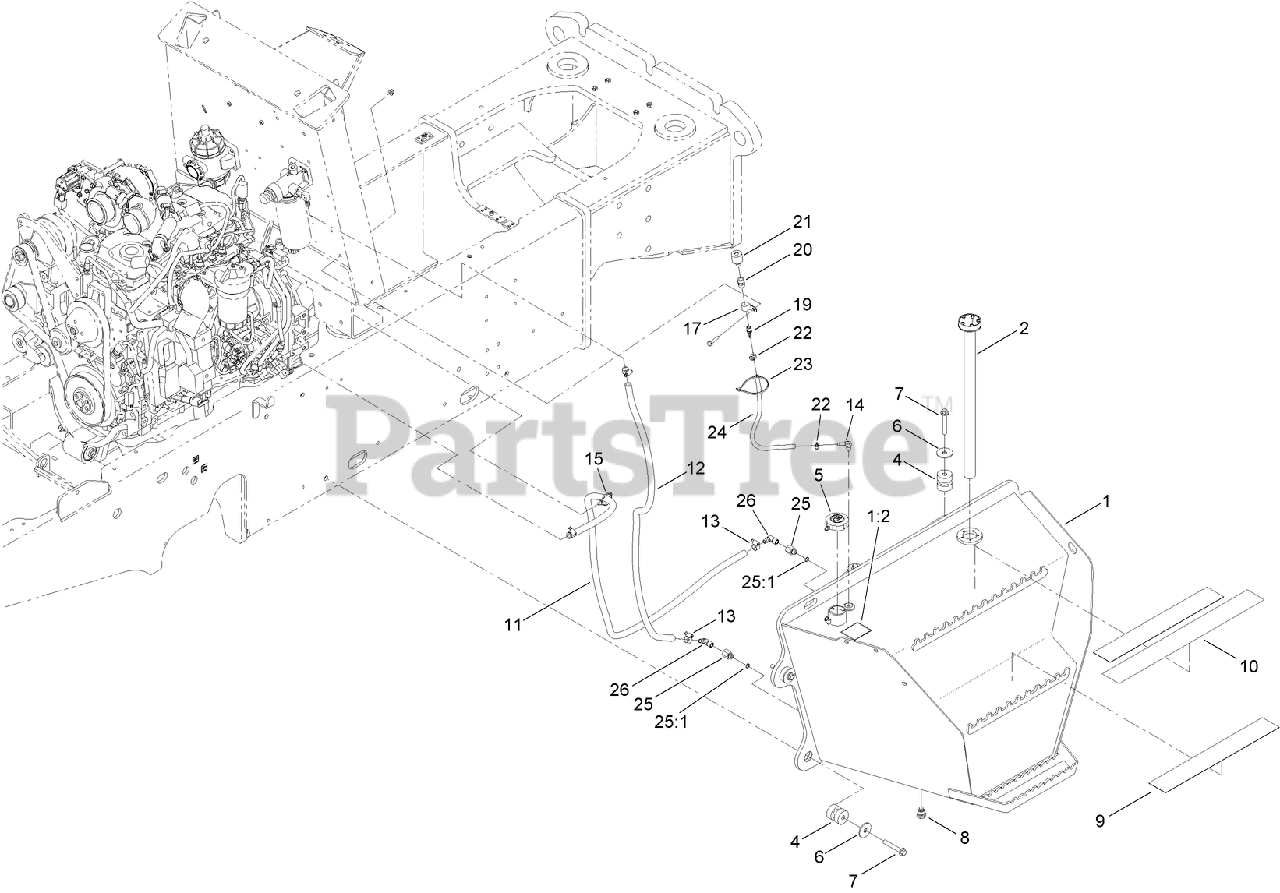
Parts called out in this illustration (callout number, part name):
1	FUEL TANK ASM
1:2	DECAL-DIESEL, ULTRA-LOW
2	SENDER-FUEL
4	ISOLATOR-MOUNTING, UNIVERSAL
5	CAP-DIESEL FUEL, NON-VENTED
6	WASHER-FLAT
7	SCREW-HHF
8	PLUG-HEX, MAGNETIC
9	TAPE-ANTI SKID, LOWER STEP
10	STRIP-ANTI SKID
11	HOSE-FUEL
12	HOSE-FUEL
13	CLAMP-HOSE, WORM DRIVE
14	STEM-90 (BARB HOSE)
15	CLIP-TIE
17	CLAMP-R
19	FITTING-STRAIGHT
20	COUPLING-PIPE (NPTF)
21	BREATHER
22	CLAMP-WORM
23	TIE-CABLE
24	HOSE-FUEL
25	FITTING-STRAIGHT
25:1	O-RING
26	ELBOW-90 DEG
